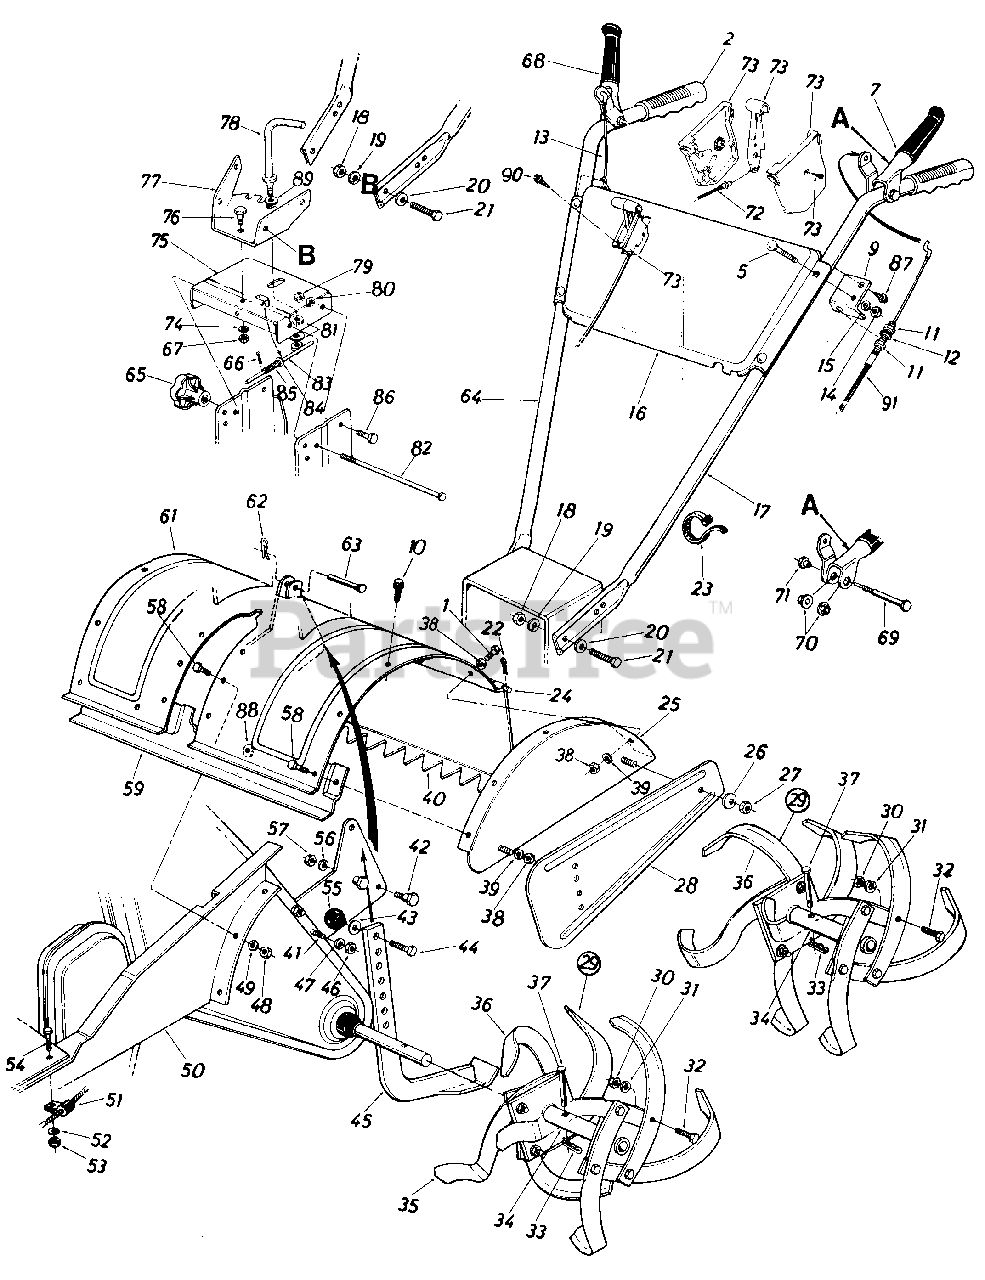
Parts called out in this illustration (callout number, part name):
1	Hex Bolt 5/16-18 x 11/4" Lg.
2	Grip
5	Carr. Bolt 5/16-18 x 1.75"
7	Clutch Grip Ass'y. L.H.
9	Clutch Cable Bracket
10	Hex Wash. S-Tap Scr. 5/16-18 x .62" Lg.
11	Hex Nut 5/16-24 Thd.
12	L-Wash. 5/16" I.D.
13	Wheel Drive Cable
14	Hex Nut 5/16-18 Thd.
15	L-Wash. 5/16" I.D.
16	Handle Panel
17	Handle-L.H.
18	Hex Nut 3/8-16 Thd.
19	L-Wash. 3/8" I.D.
20	Bell-Wash. 3/8" I.D.
21	Hex Bolt 3/8-16 x 1.00" Lg.
22	Coter Pin 3/32" Dia. x 3/4"
23	Cable Tie
24	Tiller Flap Rod
27	Hex Nut 5/16-18 Thd.
30	Hex Nut 3/8-24 Thd.
31	L-Wash. 3/8" I.D.
32	Hex Bolt 3/8-24 x 1.25" Lg.
33	Hairpin Coter
38	Hex Nut 5/16-18 Thd.
39	L-Wash. 5/16" I.D.*
41	Hex Bolt 5/16-18 x 1.0" Lg.
42	Shld. Bolt 1/2" Dia. x .426"
43	Fl-Wash. 3/8" I.D. x 518" O.D.
44	Hex Bolt 3/8-16 x 3/4" Lg.*
46	Hex Nut 5/16-18 Thd.
47	L-Wash. 5/16" I.D.
48	Hex Nut 5/16-18 Thd.
49	L-Wash. 5/16" I.D.
52	L-Wash. 5/16" I.D.
53	Hex Nut 5/16-18 Thd.
54	Hex Bolt 5/16-18 x 3/4" Lg.
55	Ball Knob 11/4" Dia.
56	L-Wash. 3/8" I.D.
57	Hex Nut 3/8-16 Thd.
58	Hex Bolt 5/16-18 x .75" Lg.
62	Hairpin Coter
63	Clevis Pin 3/8" Dia.
64	Handle-R.H.
65	Hand Knob
66	Coter Pin 1/16" Dia. x .75" Lg.
67	Hex Cent. L-Nut 3/8-16 Thd.
68	Clutch Grip Ass'y.R.H.
69	Shoulder Bolt .38" Dia. x 1.53" Lg.
70	Hex Flange Plastic Bearing
71	Shoulder Nut 1/4-20 Thd.
72	Throttle Control Wire
73	Throttle Control Box Ass'y.
74	Bell-Wash. .40" I.D.
79	Hex Cent. L-Nut 3/8-16 Thd.
80	Bell-Wash. .40" I.D. x .88" O.D.
81	Bell-Wash. 1/2" I.D. x 1.00" O.D.
82	Lock Pin 5/16" Dia. x 8"
83	Lower Sliding Ass'y.
84	Fl-Wash. .291" I.D. x .62" O.D.
85	Compression Spring .36" O.D. x 1.00" Lg.
86	Shoulder Bolt 1/2" Dia. x .170" Lg.
87	Hex Wash. S-Tap Scr. 1/4-20 x .50" Lg.
88	Bell-Wash. 5/16" I.D.
89	Fl-Wash. 518" I.D.
90	Self-Tap Scr. #10 x 1/2" Lg.
91	Tine Control Cable
